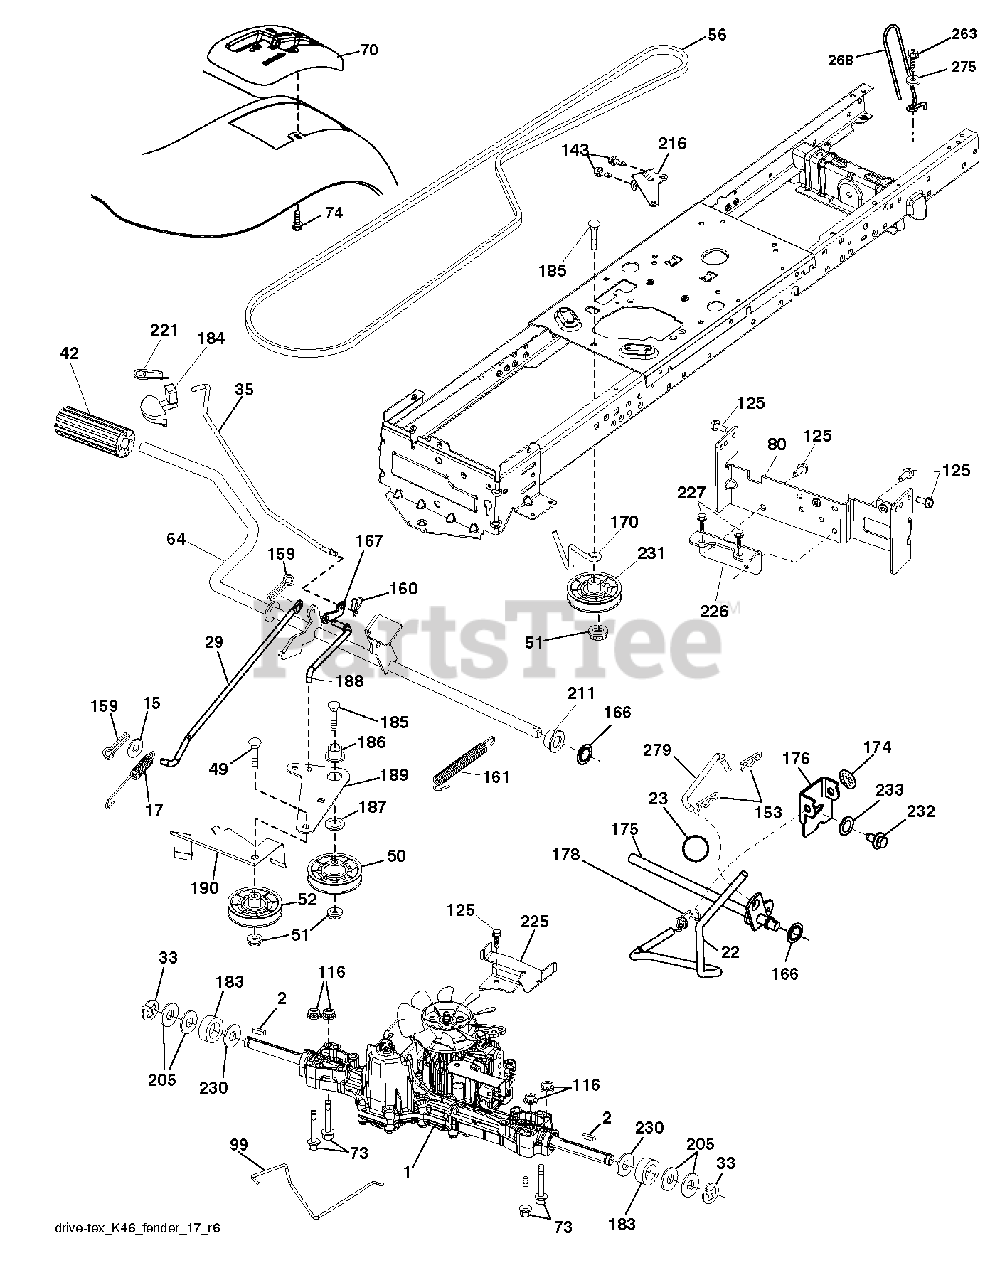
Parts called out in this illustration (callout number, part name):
2	SQUARE KEY
17	SPRING.BRAKE.K46.GREEN
22	ROD.SHIFT.FENDER.TLT.2006
23	KNOB.DUCKHEAD.1/2
29	ROD.BRAKE.K46
33	E-RING LT
35	ROD, BRAKE, PARK
42	PEDAL COVER T
49	BOLT
50	IDLER.FLAT.910.OFFSET
51	NUT LOCK FLG 3/8-16 UNC
52	IDLER.V-GROOVE.910.OFFSET
64	SHAFT.ASM.PEDAL.BRAKE.
70	CONSOLE.SHIFT.STL.HYD.BLACK
74	SCREW.HI-LO.CONSOLE
80	STRAP.TORQUE.K46.K57R.TT
99	ROD.SPRING.BYPASS.K46.LT.Z
116	NUT LOCK HEX FLANGE 5/16-18
125	SCREW
153	RETAINER M
159	COTTER PIN
160	RETAINER CLIP
161	SPRING, RETURN LT
166	NUT.PUSH.625
167	LATCH.BRAKE.SPRING
170	KEEPER.CENTER SPAN.1.688
174	NUT.PUSH.500.2006
175	SHAFT.ASM.SHFT.T2.TLT
176	ARM.CLEVIS.ROD.SHIFT
178	SPRING.SHIFT.GT2006
183	SPACER AXLE
184	HANDLE.PARKING.BRK.PRED.LT.RED
186	SPACER.RETAINER
187	WASHER 12/32X2X10GA
188	LINK.CLUTCH.GROUND.DRIVE
189	BELLCRANK.GROUND.DRIVE.TEX.
190	KEEPER.BELLCRANK.DRIVE
211	BUSHING.SHAFT.BRAKE.HAND
216	BRACKET.PULLEY.IDLER.W/TEX
221	RETAINER.SPRING.CLIP.H
225	KEEPER.BELT.TRANSAXLE.K46
226	BRACKET.MOUNT.TORQUE.K46.TLT
227	SCREW
230	WASHER.HARDENED
231	IDLER.V-GROOVE.1.688.OFFSET
232	BOLT FIN HEX 7/16-14 X 1
233	WASHER SERRATED
263	SCREW, 3/8-16X3/4
275	WASHER
279	LINK.SHIFT.
